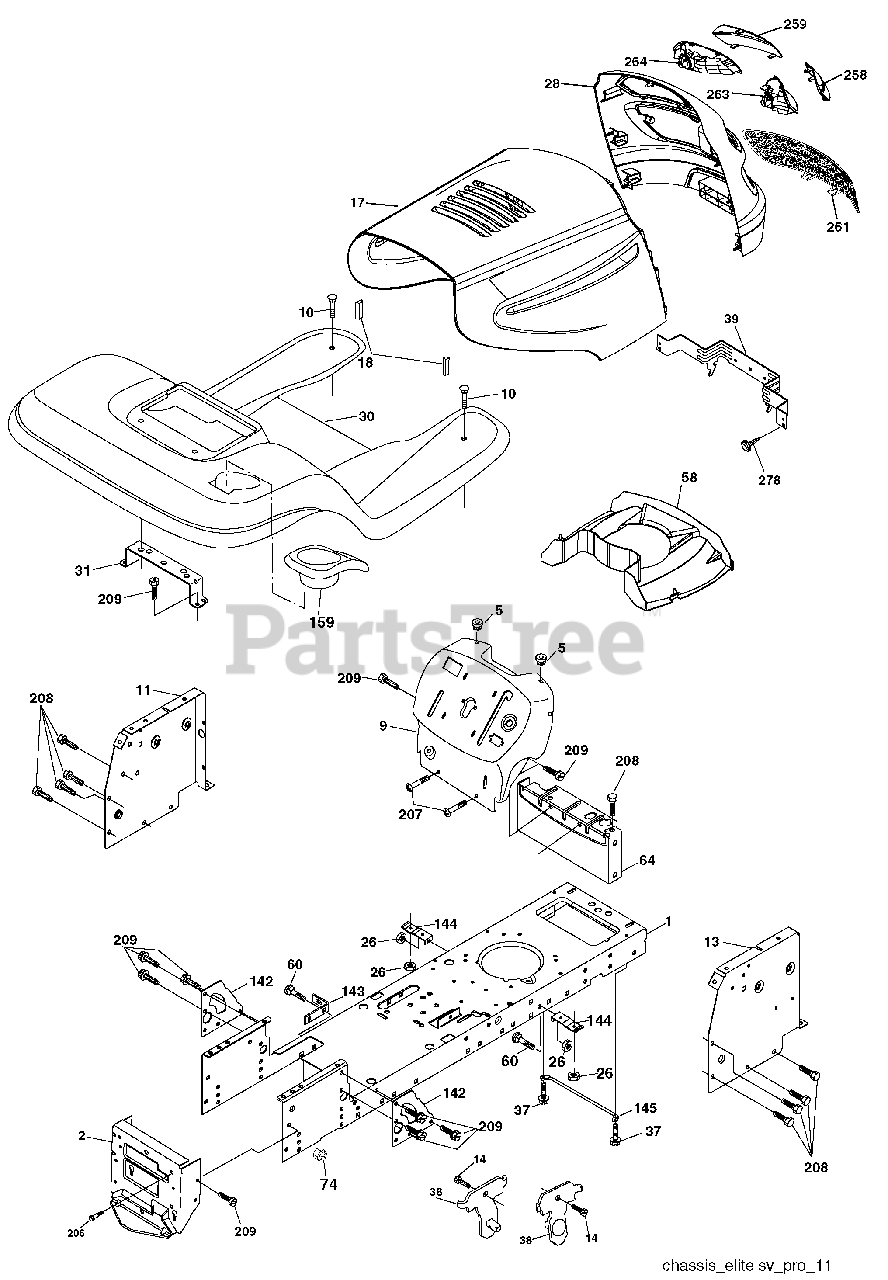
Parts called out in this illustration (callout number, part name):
1	Chassis
2	Drawbar
5	Bumper Hood/Dash
9	Dash P/L
10	Bolt Carriage 3/8-16 x 1
11	Panel Dash LH
14	Screw THDROL 3/8-16 x 1/2
17	Hood
18	Bumper Hood
26	Nut Lock Hex w/Ins 3/8-16 unc
28	Grille/Lens Asm
31	Bracket Fender
37	Screw Thdrol 6/16-18 x 1/2 TYT
38	Bracket Asm Pivot Mower Rear
39	Bracket Pivot
58	Duct Air
60	Bolt RDHD SQNK 3/8-16 unc x 1
64	Dash Lower STLT
74	Nut Crownlock 3/8-16 unc
142	Plate Reinforcement STLT
143	Bracket Swaybar Chassis
144	Bracket Footrest
145	Rod Pivot Chassis/Hood
159	Cupholder
206	Bolt Shoulder 5/16-18
207	Screw Thdrol 5/16-18 x 1/2
208	Screw Thdrol 3/8-16 x 1/2
209	Screw Hexwsh Thdr 3/8-16 x 3/4
258	Lens Grille Pro RH
259	Lens Grille Pro LH
263	Bezel Grille RH
264	Bezel Grille LH
278	Screw #10 x 0.750 BOS Thread
278	Plug BTN BlK
278	Plug Domed Plastic
